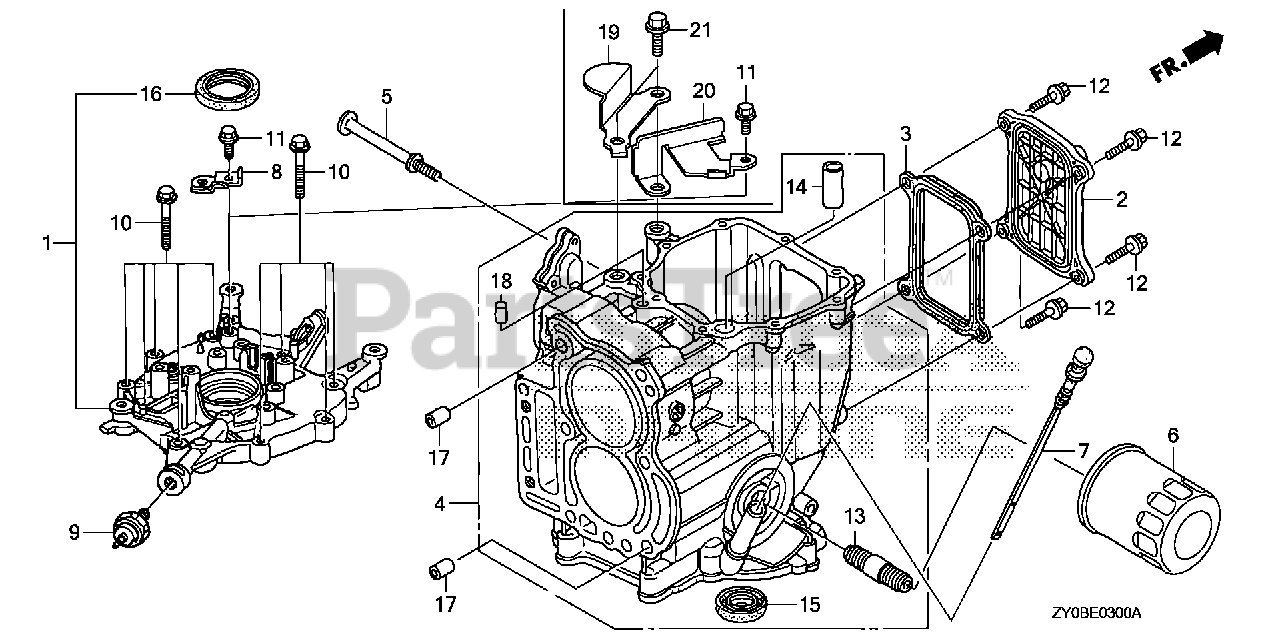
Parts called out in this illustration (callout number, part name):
1	COVER ASSY., CRANKCASE (800)
2	COVER, CRANKCASE SIDE
3	GASKET, CRANKCASE SIDE COVER
4	BLOCK ASSY., CYLINDER (000) *NH8* (DARK GRAY)
5	STOPPER, ENGINE SIDE
6	FILTER, OIL (TOYO ROKI)
6	FILTER, OIL (DENSO)
7	DIPSTICK, OIL
8	BRACKET, CLIP B
9	SWITCH ASSY., OIL PRESSURE
10	BOLT, FLANGE (6X28)
11	BOLT, FLANGE (6X14) (CT200)
12	BOLT, FLANGE (6X22) (CT200)
13	HOLDER, OIL FILTER
14	PIN, DOWEL (14X20)
15	OIL SEAL (28X45X8)
16	OIL SEAL (35X50X8) (NOK)
17	PIN, DOWEL (10X12)
18	PIN B, DOWEL (8X14)
